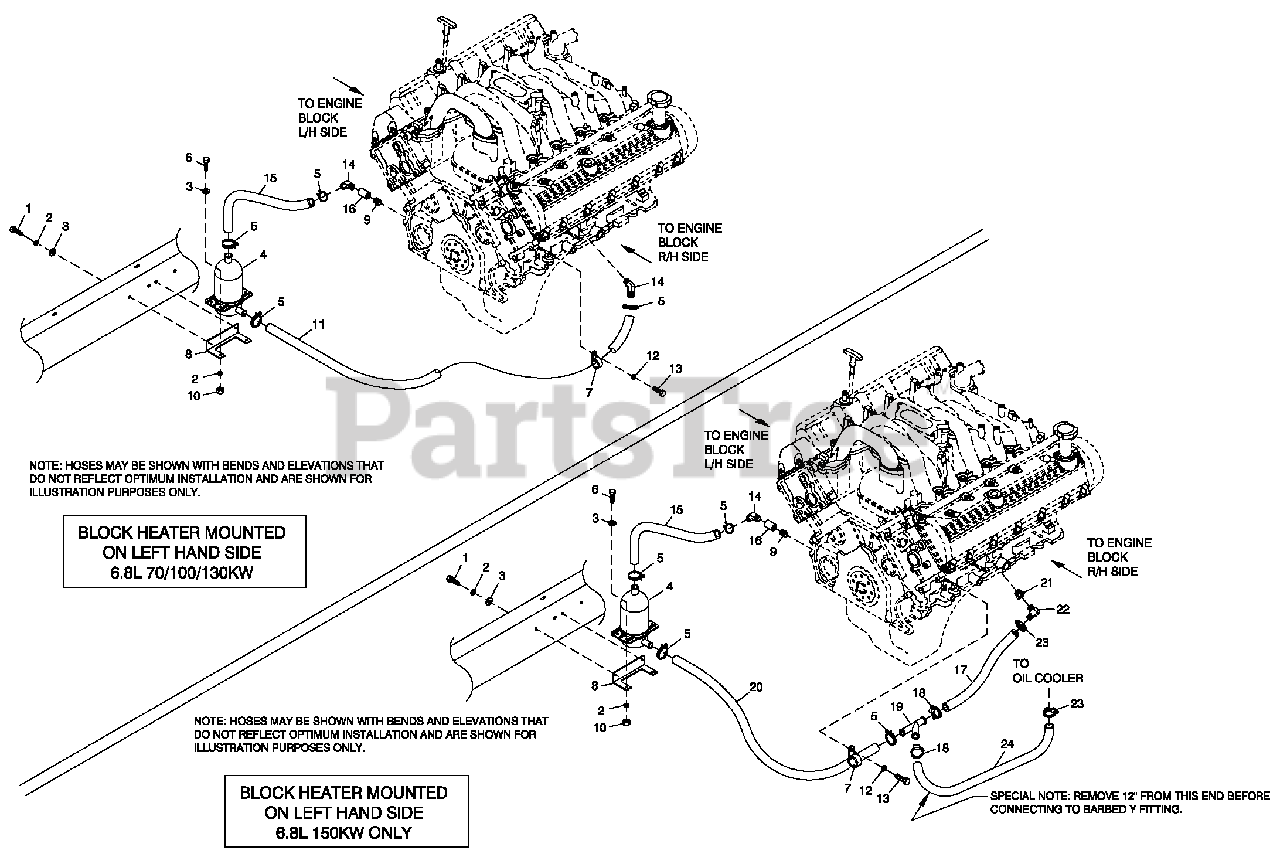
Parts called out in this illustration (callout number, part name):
1	SCREW HHC M6-1.0 X 16 G8.8
2	WASHER LOCK M6-1/4
3	WASHER FLAT 1/4 ZINC
4	HEATER ENG 1500W 120V
5	CLAMP HOSE 7/8" OD DOUBLE WIRE
6	SCREW HHC M6-1.0 X 20 G8.8
7	CLAMP VINYL 1.06 X .406 Z
8	BRACKET HEATER
9	NIPPLE CLOSE 3/8NPT X 1 VIBRA
10	NUT HEX M6-1.0 G8 YEL CHR
11	HOSE COOL 5/8 ID 20R3 (33"LG)
12	WASHER LOCK M8-5/16
13	SCREW HHC M8-1.25 X 16 G8.8
14	BARBED EL 45 3/8NPT X 5/8OD
15	HOSE PREFORMED BLOCK HEATER
16	COUPLING FULL 3/8-18
17	HOSE 3/4 ID SAE-30R2 (8"LG) (150KW ONLY)
18	CLAMP HOSE #10.56-1.06 (150KW ONLY)
19	BARB Y UNIVERSAL 5/8-3/4 HOSE (150KW ONLY)
20	HOSE COOL 5/8 ID 20R3 (24"LG) (150KW ONLY)
21	ADAPTER 1/2"NPT X 3/8"NPT (150KW ONLY)
22	BARBED EL 90 1/2NPT X 3/4 HOSE (150KW ONLY)
23	CLAMP HOSE #10.56-1.06 (150KW ONLY)
24	HOSE OIL COOLER PREFORMED 3/4 (150KW ONLY) (SEE SPECIAL NOTE)
